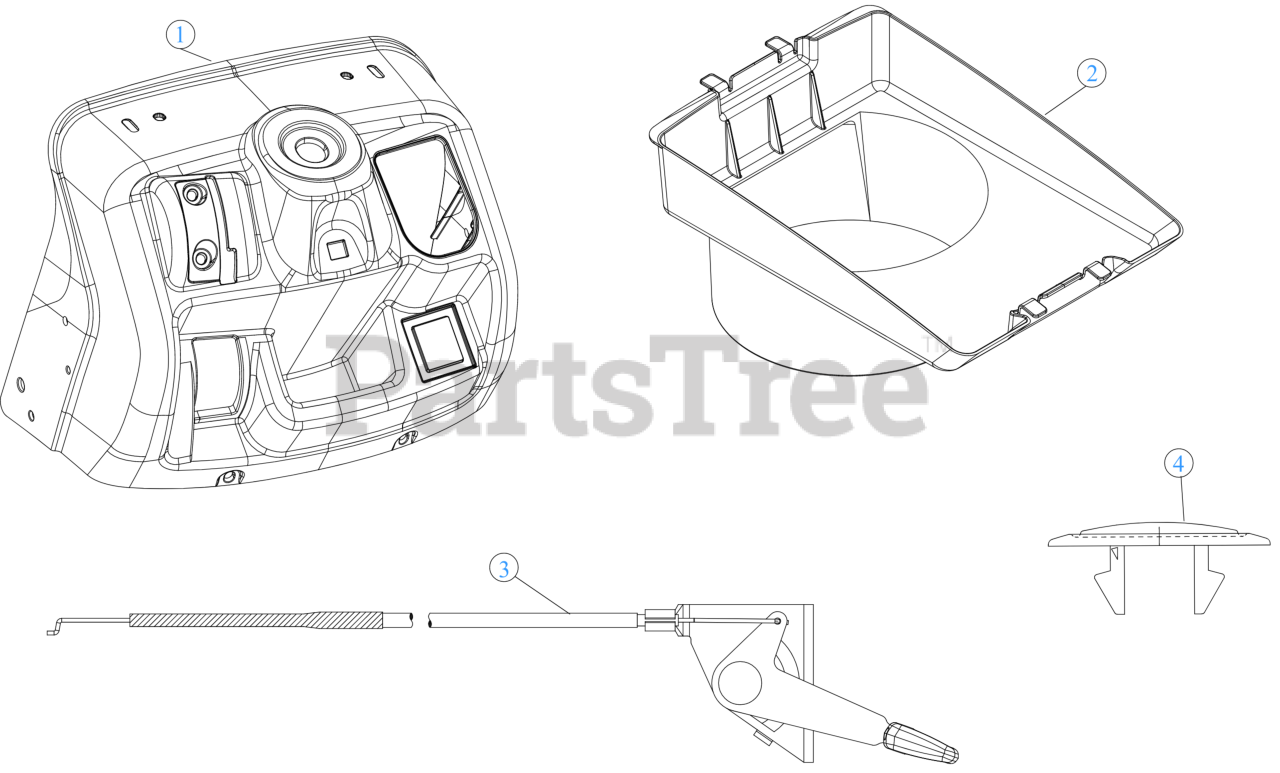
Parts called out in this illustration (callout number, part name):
1	UPPER DASH
2	HOOD PLENUM
3	THROTTLE CABLE 28" x 1.1
4	CHOKE PLUG
